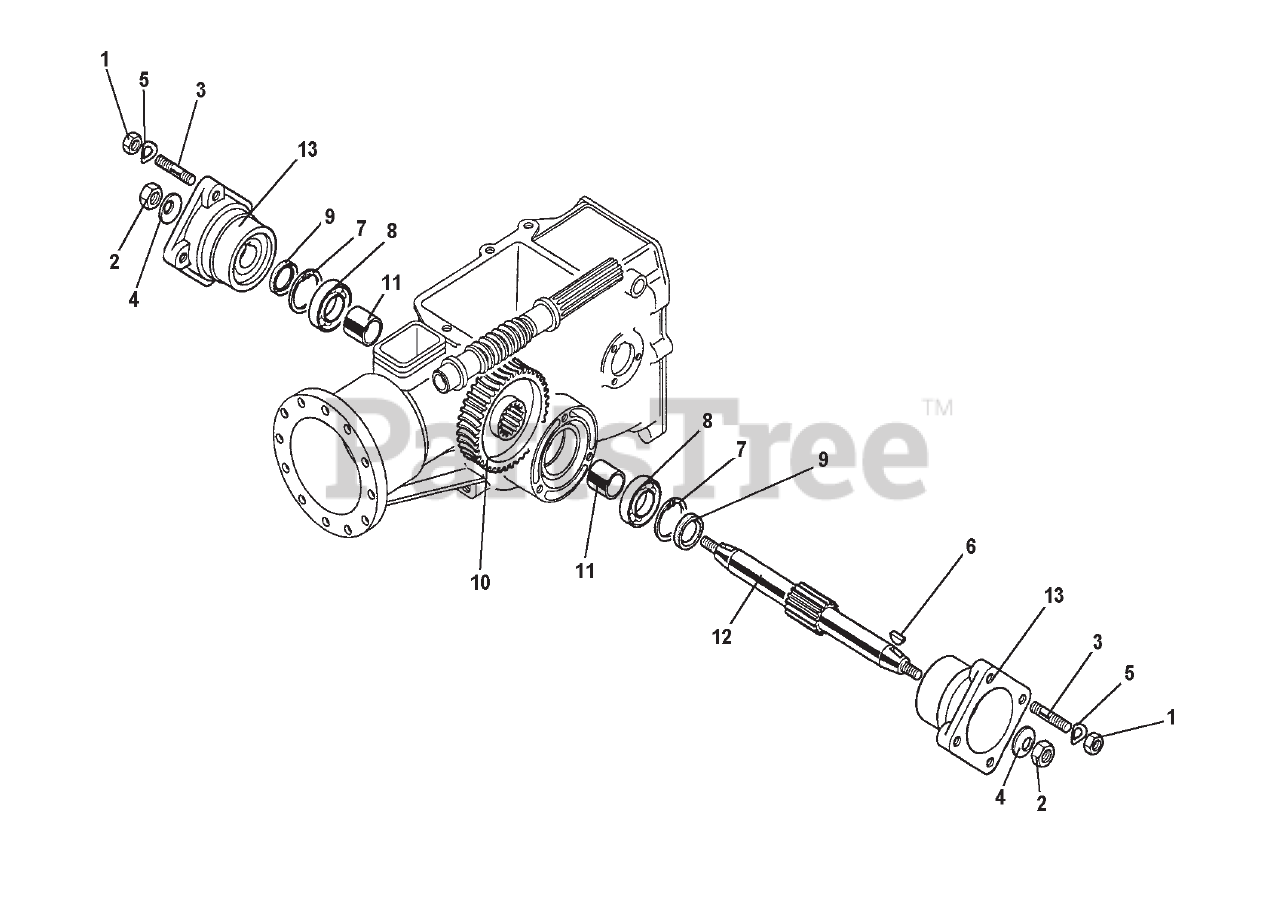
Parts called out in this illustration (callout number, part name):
1	NUT, M10
2	NUT, SELF LOCKING, M12
3	STUD, M10X40X22X14
4	SUPER WASHER, M12
5	WASHER, LOCK, M10.5
6	KEY, M6X10
7	CIRCLIP, INTERNAL
8	BEARING, M25X52X15
9	OIL SEAL, M25X52X10
11	SPACER
12	WHEEL SHAFT
13	HUB, WHEEL WITH STUDS
